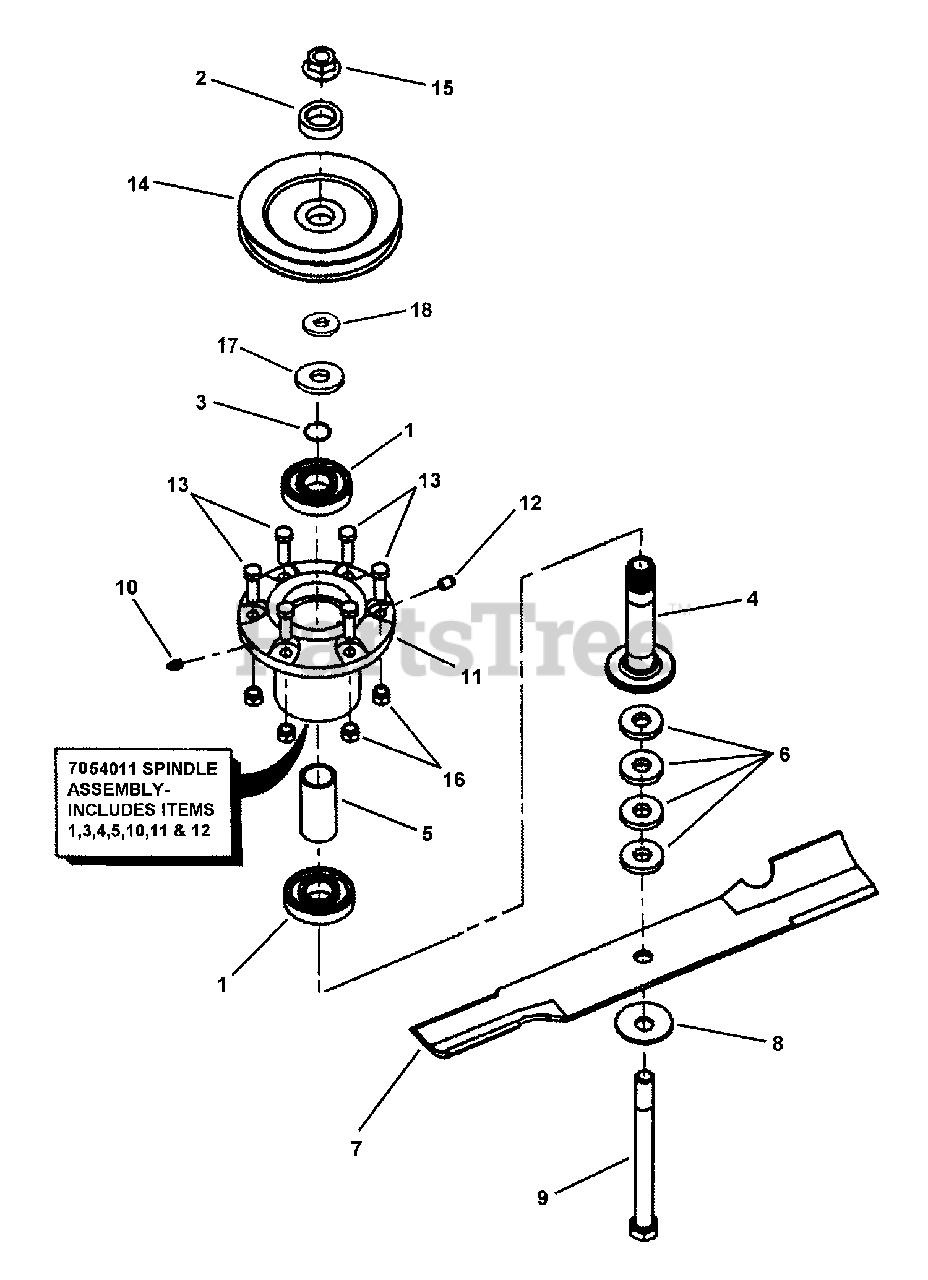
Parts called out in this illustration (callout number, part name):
1	BEARING, Sealed
2	WASHER, Spindle
3	SNAP-RING, Spindle Shaft
4	ASSEMBLY, Spindle Shaft
5	SPACER, Bearing
6	SPACER, Blade
7	BLADE, 18"
7	BLADE, 16-1/2"
8	WASHER, Beveled
9	BOLT, 5/8-11 x 7-1/2" Hex Head Cap, GR 5
10	FITTING, 1/4-28 Straight Lube
11	HOUSING, Cutter
12	VENT, Spindle
13	BOLT, 3/8-16 x 1-1/4" Rib Necked
14	PULLEY, 5-3/4" O.D.
15	NUT, 5/8-11 Hex Flange Lock, GR B
16	NUT, 3/8-16 HEX NYLON LOCK
17	SEAL, Nylos
18	WASHER
